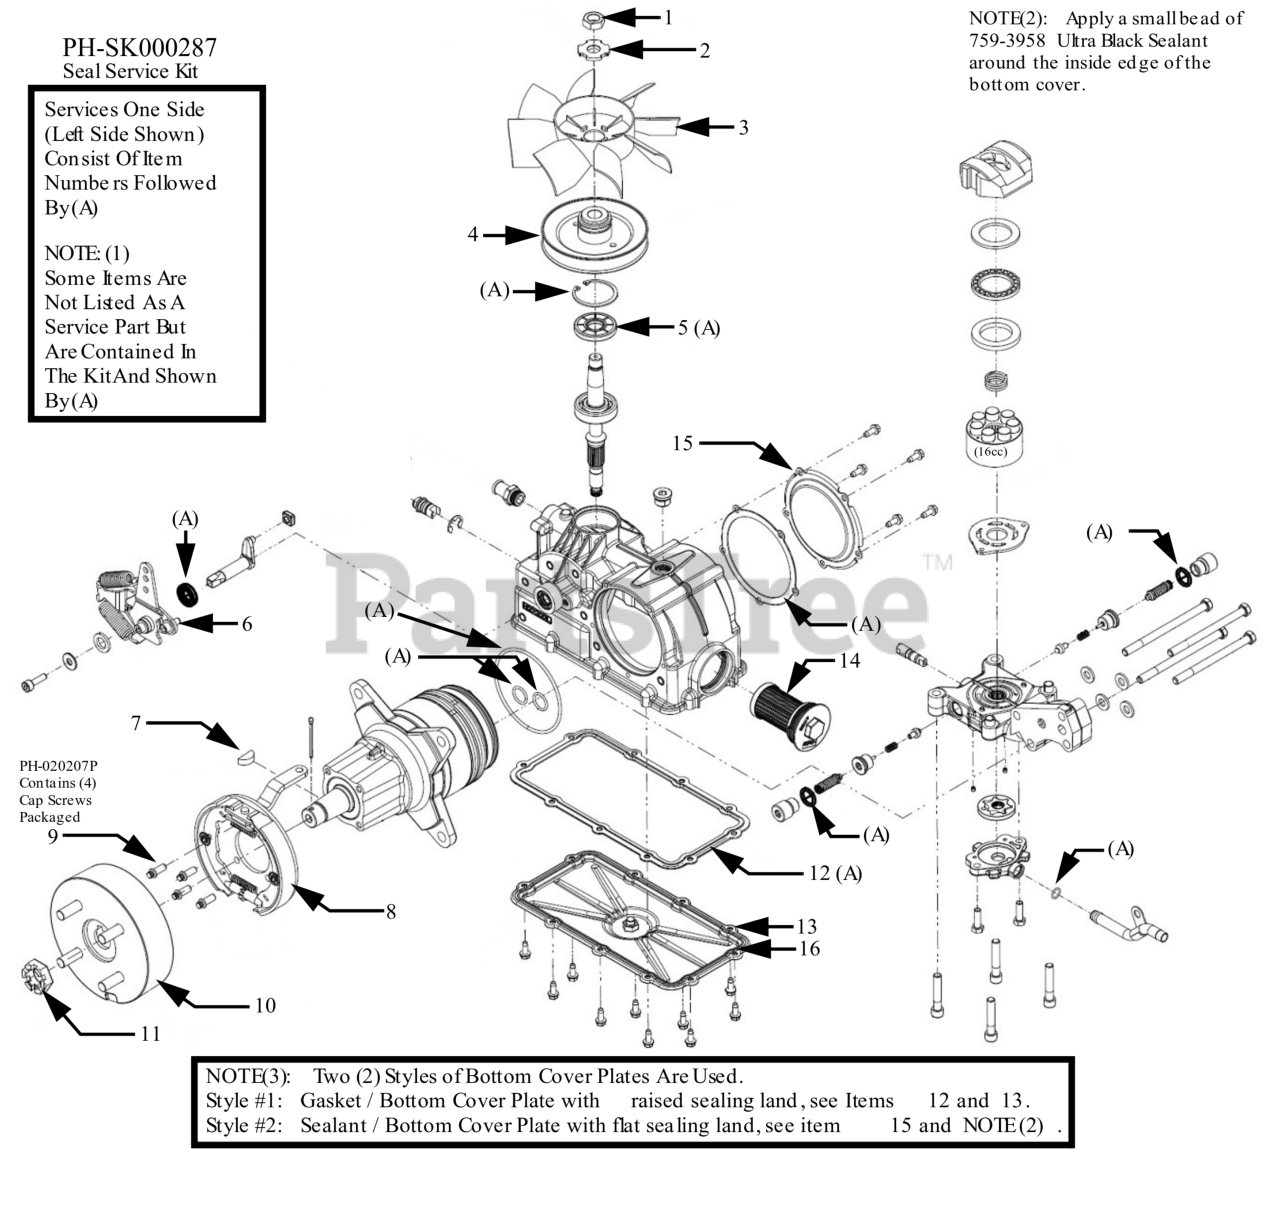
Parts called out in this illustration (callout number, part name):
5	SEAL KIT
6	SERVICE KIT-RTN (LH)
7	WOODRUFF KEY
8	BRAKE ASSEMBLY-ON HOLE LEVER
9	SCREW-CAP (QTY 4)
10	DRUM-4 BOLT BRAKE
11	NUT-SLOTTED
12	BOTTOM COVER GASKET
13	BOTTOM COVER
15	SIDE COVER PLATE
16	BOTTOM COVER
A	SEAL SERVICE KIT
